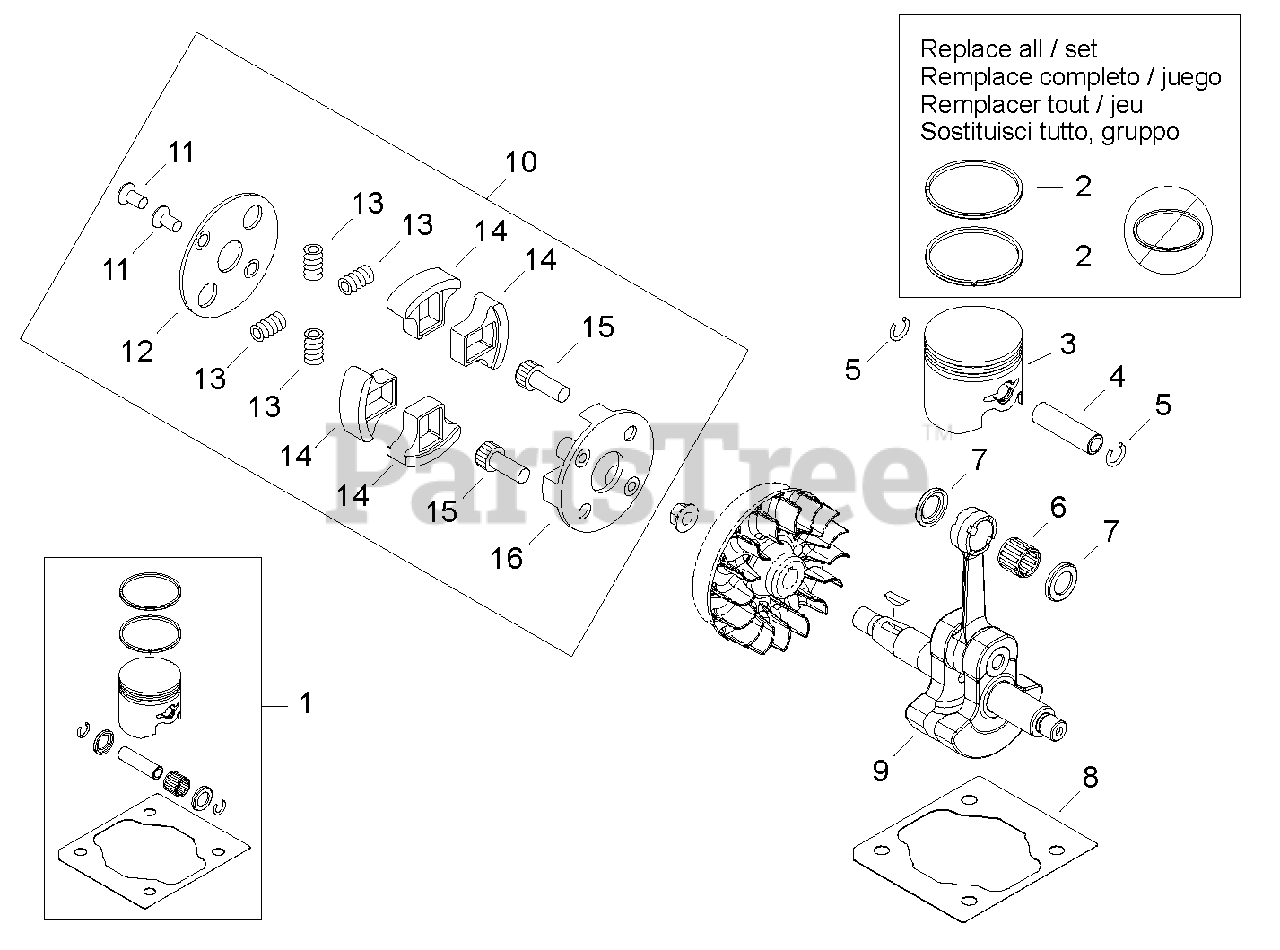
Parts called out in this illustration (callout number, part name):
1	PISTON KIT
2	RING, PISTON
3	PISTON
4	PIN, PISTON
5	RING, SNAP
6	BEARING, NEEDLE 9
7	WASHER, THRUST 9
8	GASKET, CYLINDER
9	CRANKSHAFT
10	CLUTCH ASSY
11	BOLT 5
12	PLATE, CLUTCH
13	SPRING, CLUTCH
14	SHOE, CLUTCH
15	BOLT, CLUTCH
16	BOSS, CLUTCH
